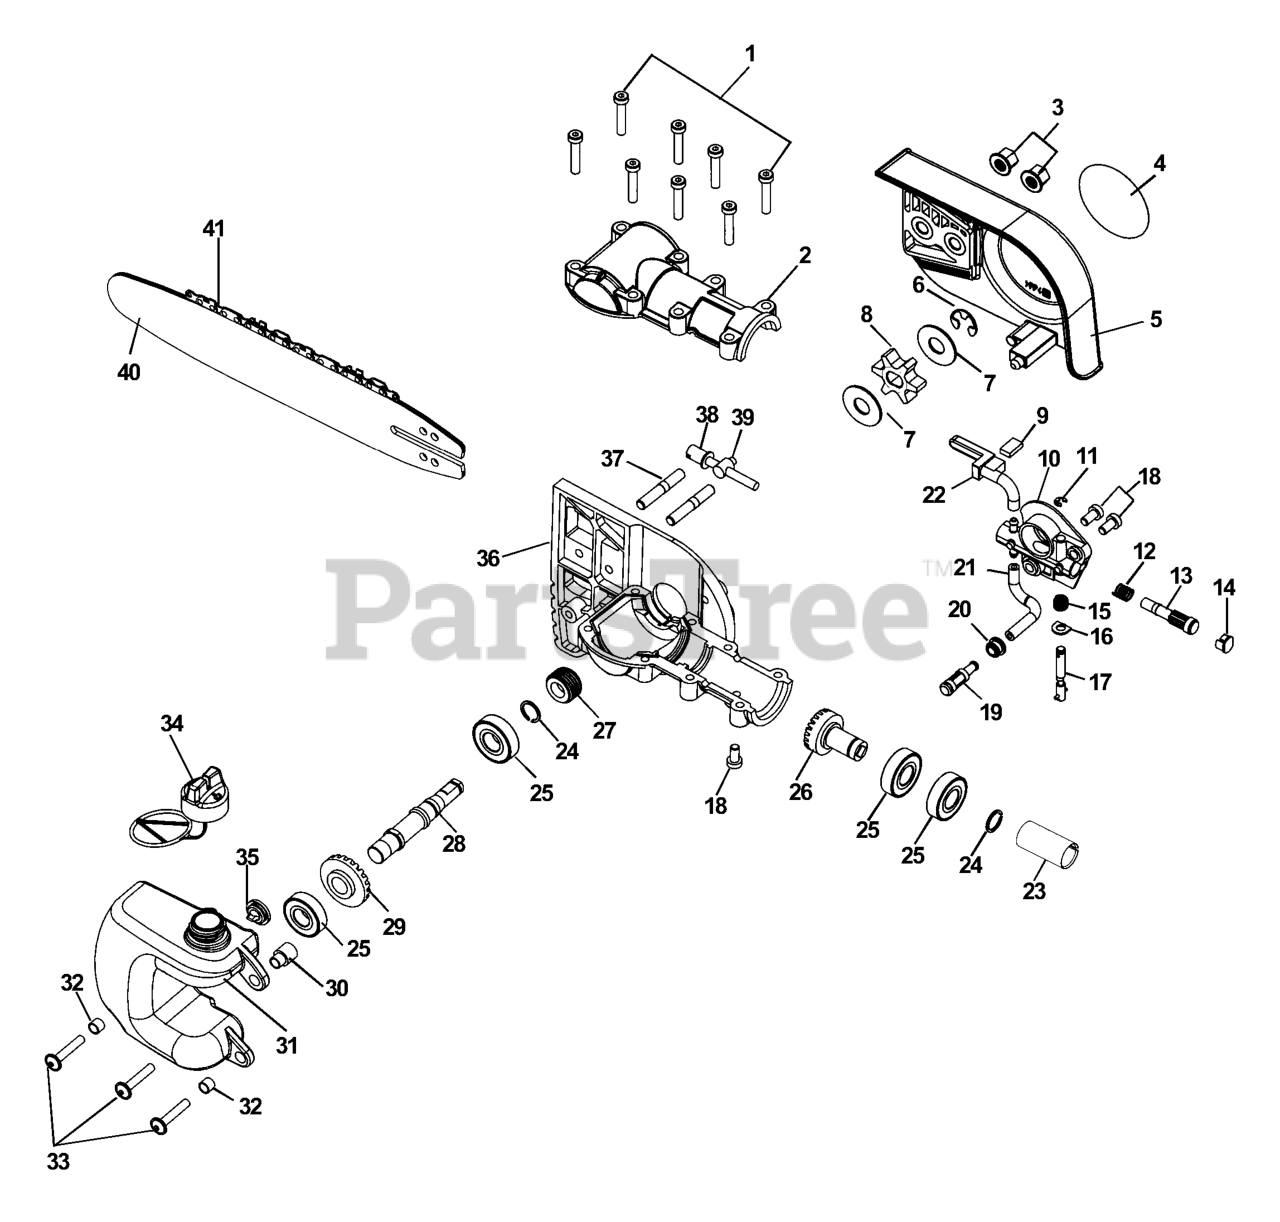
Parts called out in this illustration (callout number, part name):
1	SCREW - 5X25
2	CASE, GEAR - UPPER
3	NUT - 6 -- FLANGE
4	LABEL - ECHO
5	GUARD, SPROCKET
6	RING, RETAINING
8	SPROCKET, DRIVE
9	PAD, FOAM
10	AUTO-OILER ASSY
11	RING, RETAINING
12	SPRING, PLUNGER
13	PLUNGER ASSY
14	CAP, OIL PUMP
17	NEEDLE, ADJUST
18	SCREW - 5X10
19	FILTER, OIL
20	GROMMET
21	PIPE - 3X6X75 -- BLACK
22	PIPE, OIL OUTLET
23	COLLAR - 22
24	RING, RETAINING - 12
25	BEARING, BALL - 6001
26	GEAR - BEVEL
27	GEAR - WORM
28	GEAR - SHAFT
29	GEAR - BEVEL
31	TANK, OIL
33	SCREW - 5X20
34	CAP ASSY
36	CASE, GEAR - LOWER
37	STUD - 6
38	SCREW, TENSIONER
39	TENSIONER, CHAIN
40	GUIDE BAR
41	CHAIN, SAW
